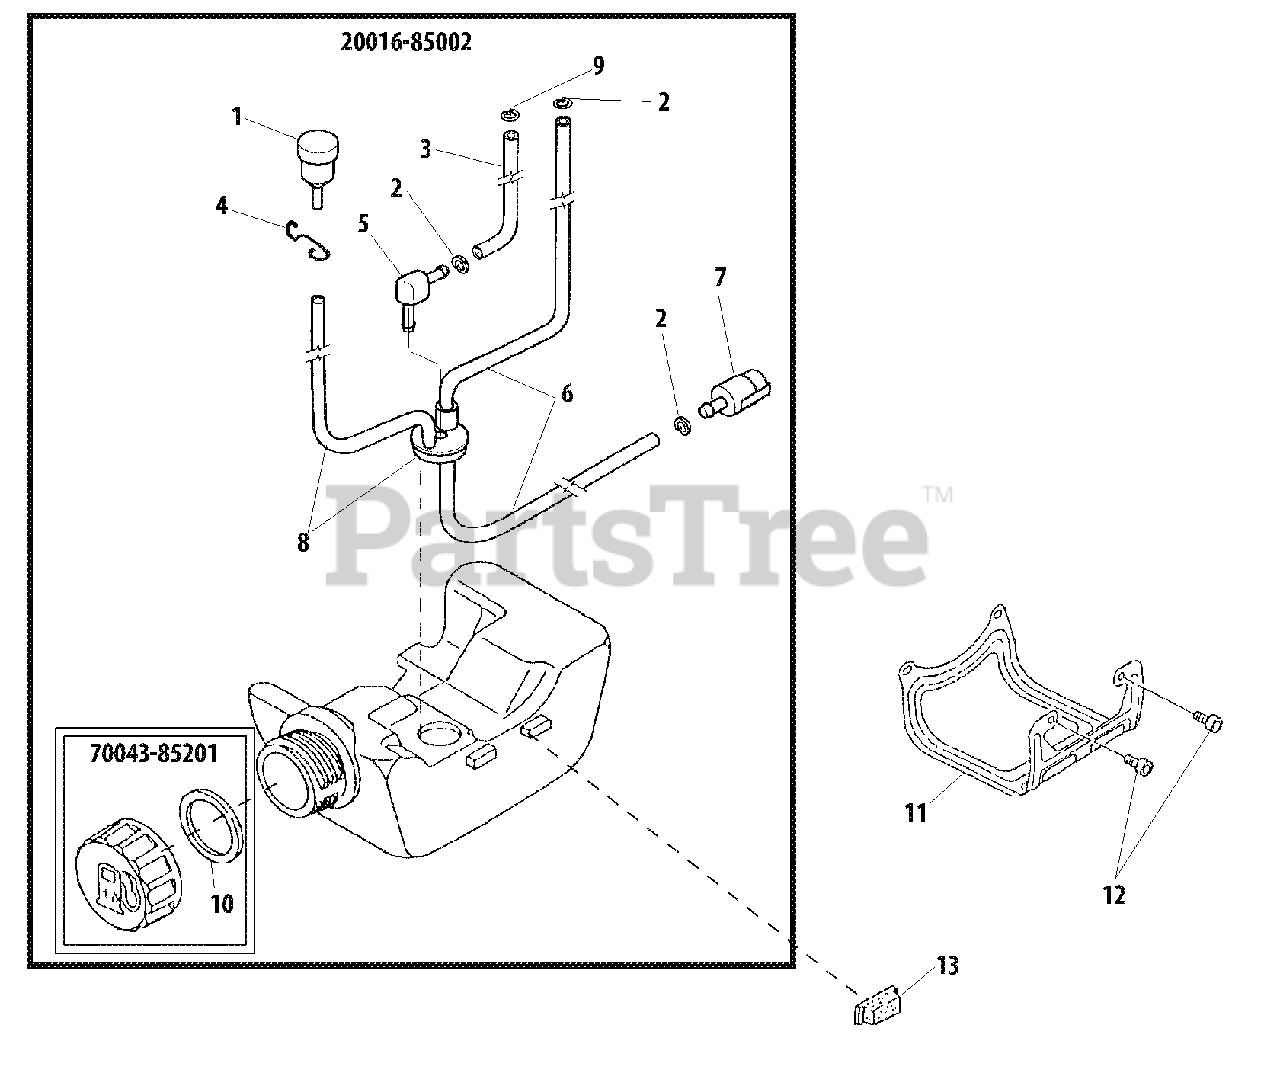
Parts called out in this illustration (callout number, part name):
1	VENT ASSY
2	CLIP Ø6
3	PIPE, FUEL RETURN
4	CLIP, VENT ASSY
5	CONNECTOR, PIPE
6	PIPE, FUEL
7	FILTER, FUEL 125-528
8	GROMMET
9	CLIP, SPRING Ø5.2
10	GASKET, FUEL CAP
11	GUARD, METAL FUEL TANK
12	BOLT M5×12
13	CUSHION, FUEL TANK
20016-85002	FUEL TANK ASSY
70043-85201	CAP ASSY, FUEL
